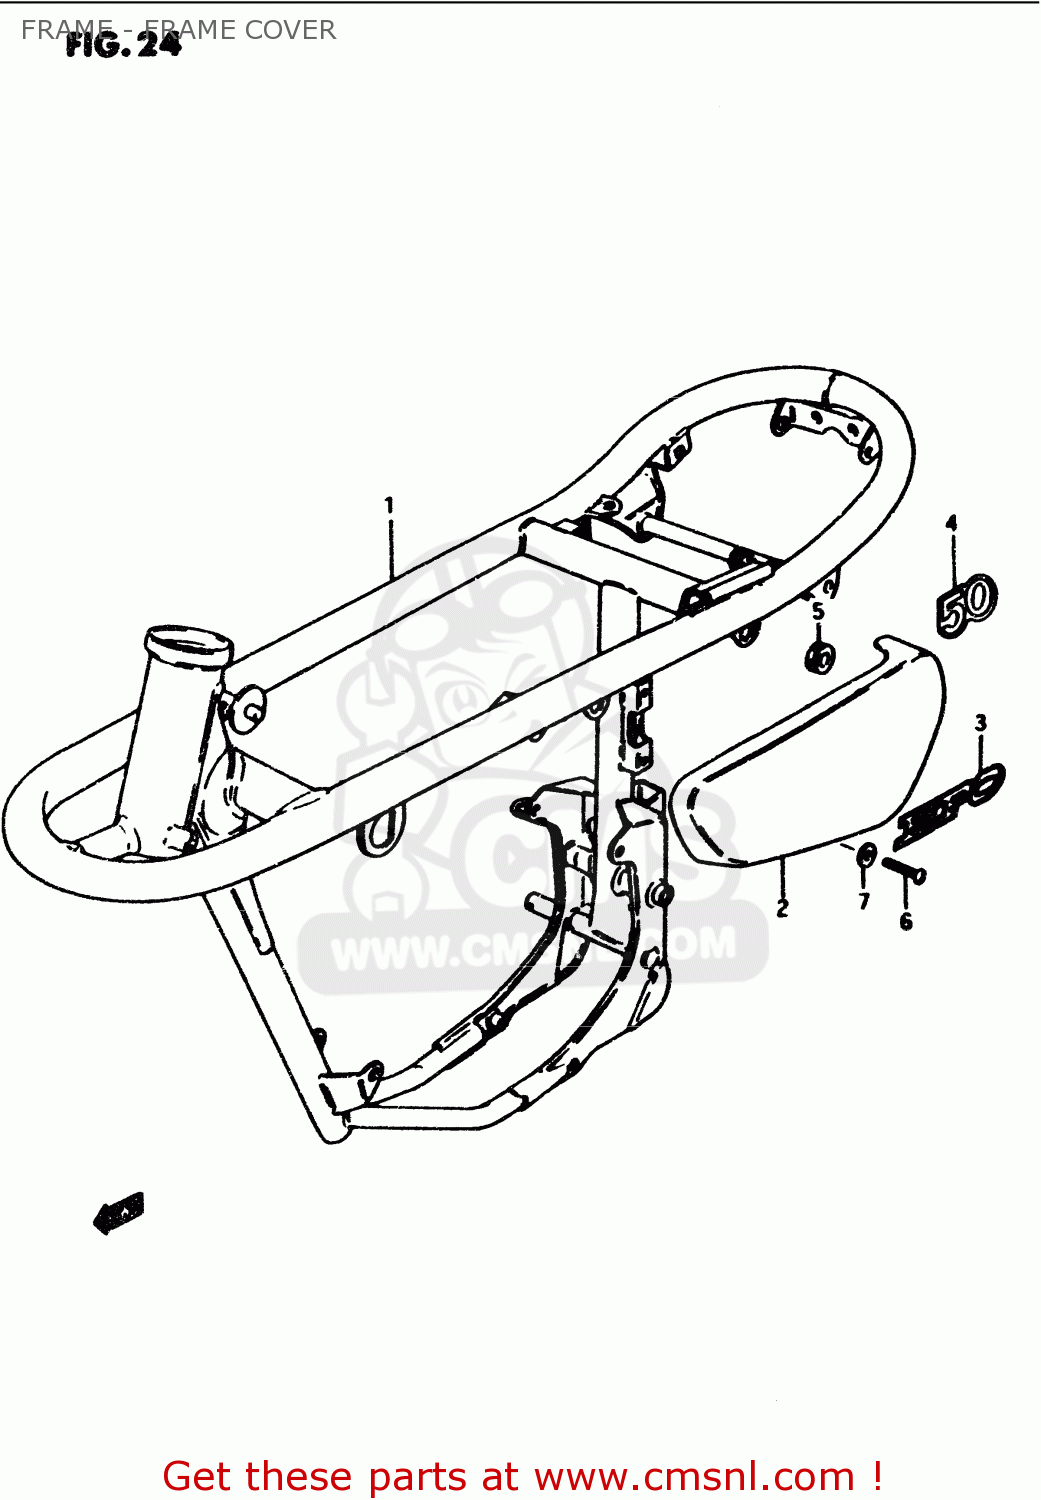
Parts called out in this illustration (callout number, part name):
1	FRAME (PEARL)
2	COVER,FRAME,L(BLACK)
3	EMBLEM
4	EMBLEM (RED)
5	CUSHION
6	SCREW
7	WASHER (6.5X18X1.6)
